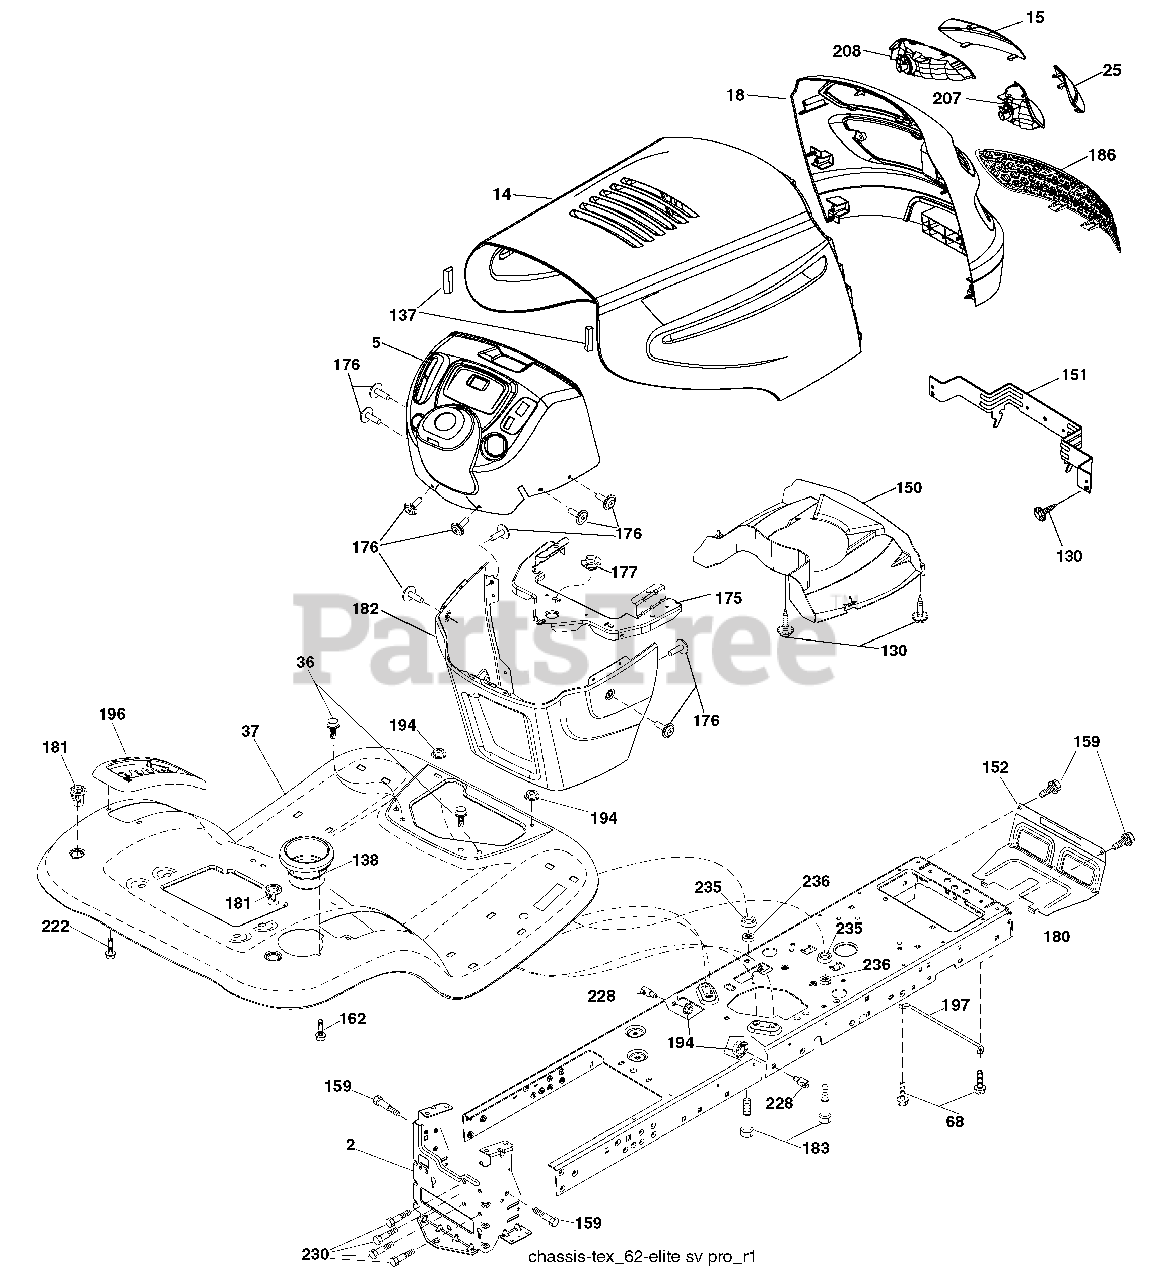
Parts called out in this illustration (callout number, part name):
2	Drawbar
14	Hood
15	Lens Grille LH
18	Grille
25	Lens Grille RH
36	Screw 5/16-18 x 3/4
37	Fender
68	Screw THDROL 5/16-18 x 1/2
130	Screw 10 x .750 BOS Thread
137	Bumper Hood
138	Cupholder
150	Duct Heat Hood
151	Bracket Pivot
152	Shield Browning/Debris
159	Screw Hexwsh Thdrol 3/8-16 x 3/4
162	Screw Hex Wsh Hi-Lo 1/4 x 1/2 unc
175	Crossmember
176	Screw 10-24 x 5/8 Wshd Qdrx
177	Bushing Steering
181	Bushing Mtg. Fender Crgo.
182	Dash Lower
183	Bolt Fin Hex 5/16-18 x 1-1/4
194	Nut Lock Hex Flange 5/16-18
196	Console Asm. Deck Lift
197	Rod Pivot Chassis
207	Bezel RH
208	Bezel LH
222	Screw Thd Roll 1/4-20 x 5/8
228	Stud Fastener
230	Bolt Shoulder 5/16-18
235	Spacer Fender
236	Nut Center Lock 5/16-18 unc
